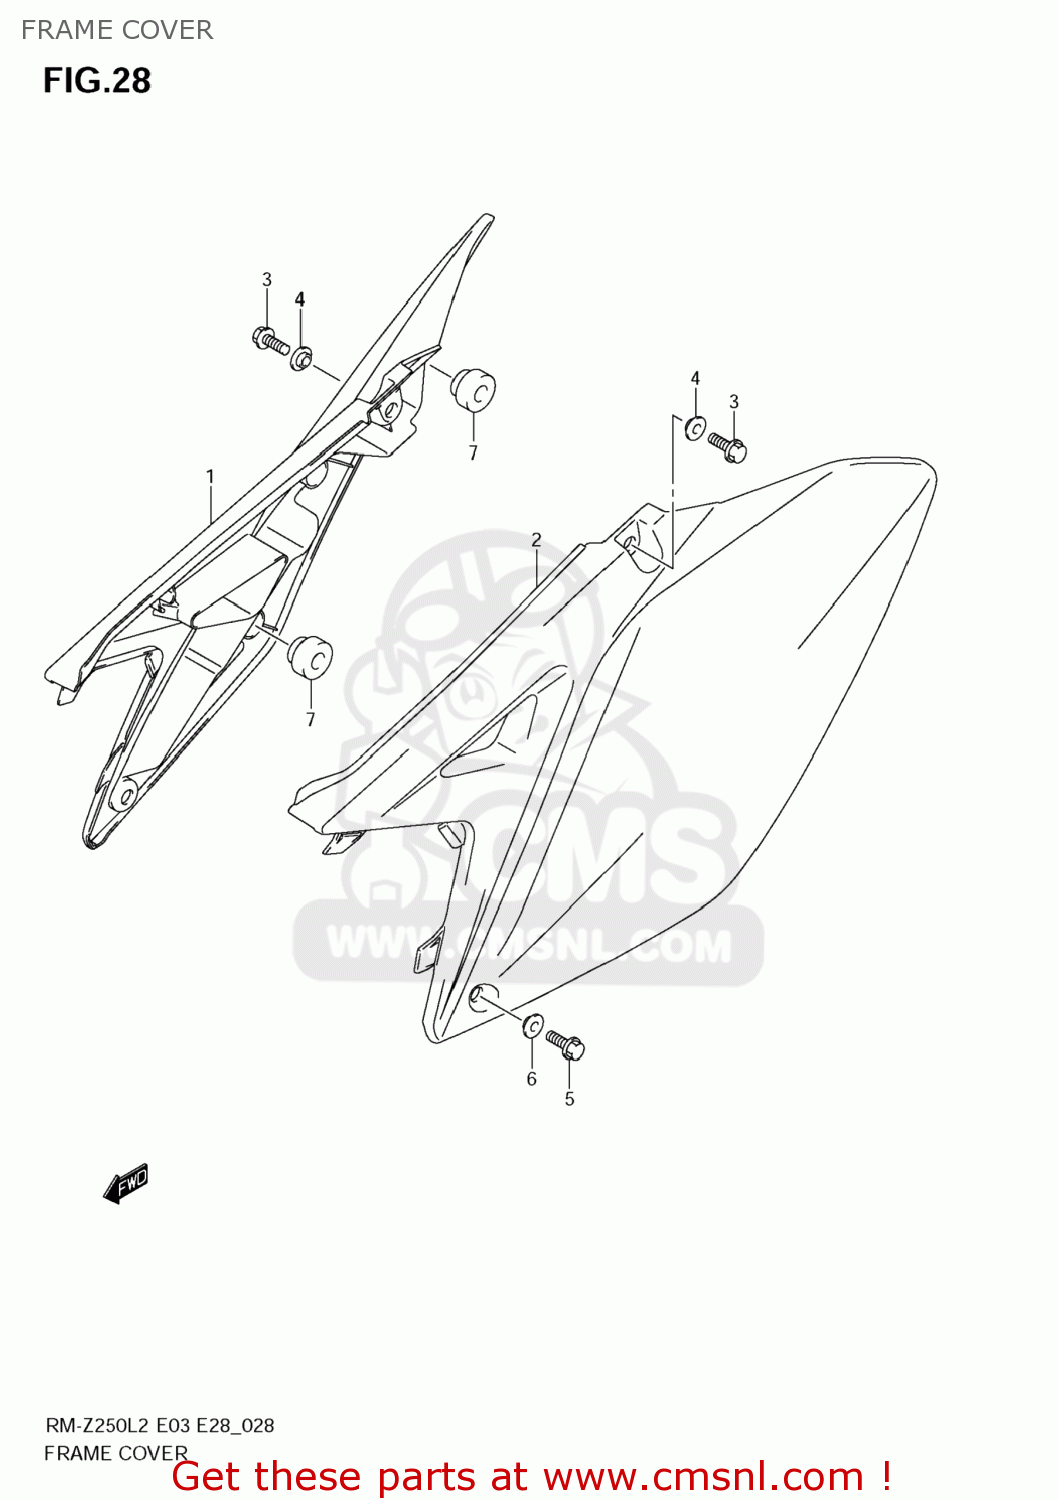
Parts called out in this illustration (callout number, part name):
1	COVER,FRAME,R
2	COVER,FRAME,L
3	BOLT
4	WASHER
5	BOLT
6	WASHER
7	CUSHION
